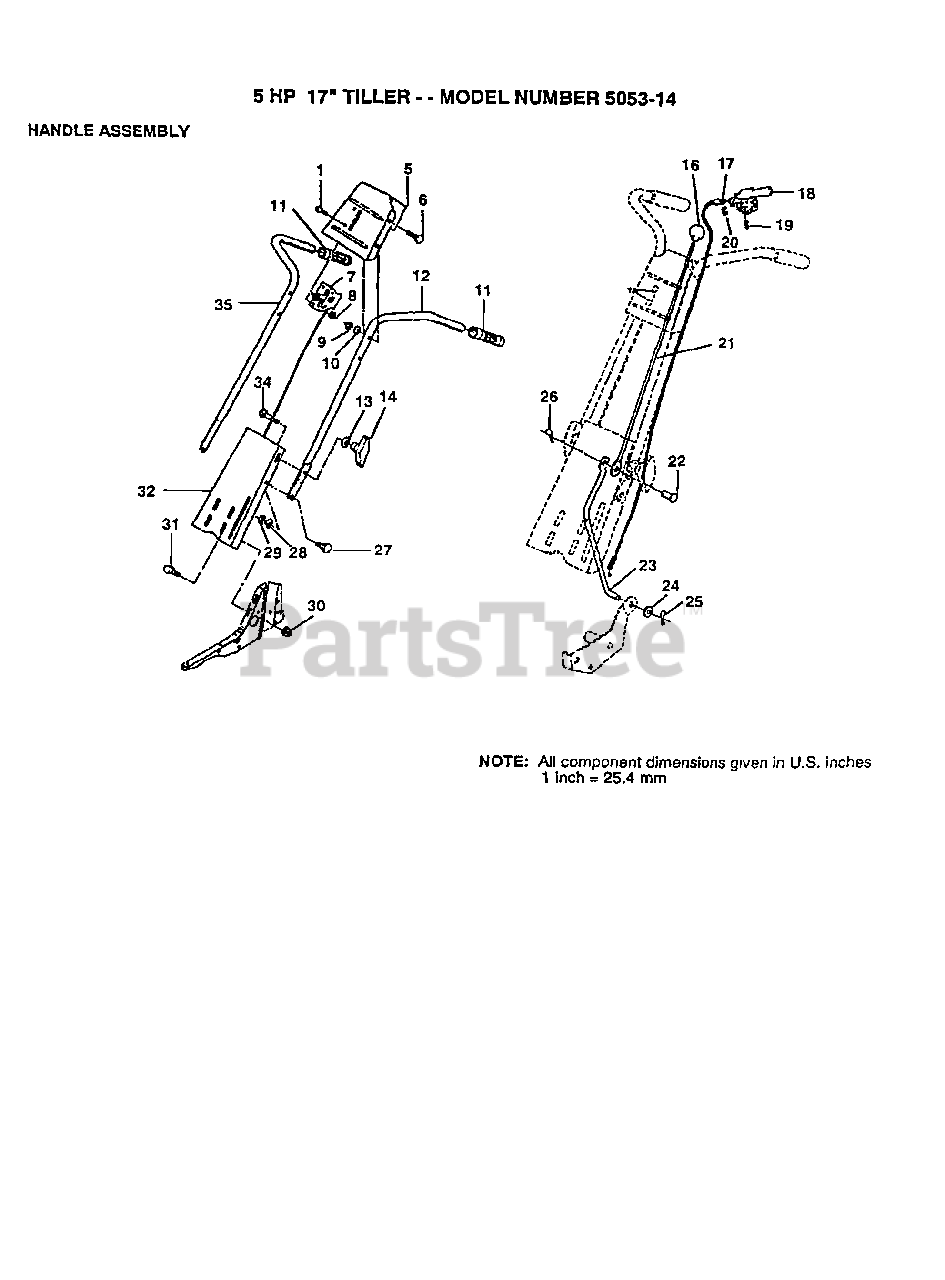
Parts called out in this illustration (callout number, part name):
1	SCREW
6	BOLT
10	WASHER
13	WASHER
17	CABLE CLUTCH T
18	CONTROL LEVER TI
19	SCREW
20	E-RING
21	ROD REVERSE TI
22	RIVET.RD.HD.DRILL
23	REVERSE ROD TI
24	WASHER
25	COTTER PIN
28	LOCKWASHER
29	NUT.HEX.5/16-18
30	NUT
31	BOLT
32	"PANEL,HDLE TI"
34	BOLT
